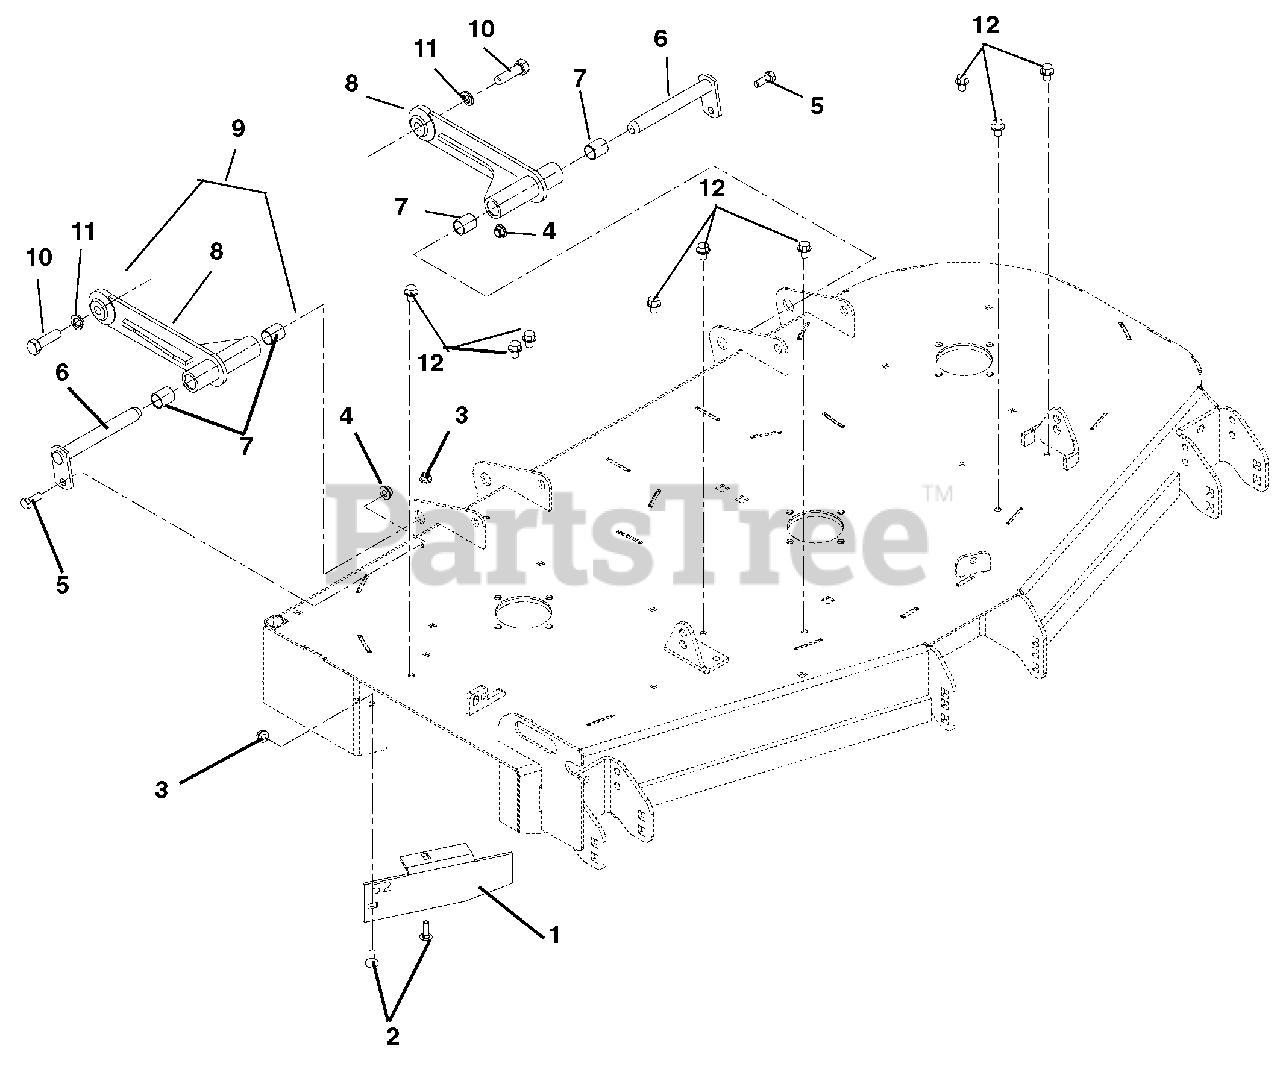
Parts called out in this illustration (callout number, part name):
1	BAFFLE, 52" DISCHARGE
1	BAFFLE, 60" DISCHARGE
1	BAFFLE, 44/48" SIDE DISCHARGE
2	@BLT-RDHDSQNK .31-18X1.00 G5YZ
3	@NUT-LK-NYL-FLG .31-18 YWZC
4	@NUT-LK-NYL-FLG .38-16 YWZC
5	@BLT-HEX .38-16X1.00 GR5 YWZC
6	WELDMENT, MOWER MTG. PIN
7	BRG, .750 X .875 X 1.000
8	DECK PUSHER ARM WMT - BLACK
9	DECK PUSHER ARM ASSEMBLY
10	@BLT-HEX .50-13X1.75 GR5 YWZC
11	@WSHR-LK .50X.125 REG YWZC
12	@SCR-TAP .38-16X.50 HWH TR YWZ
